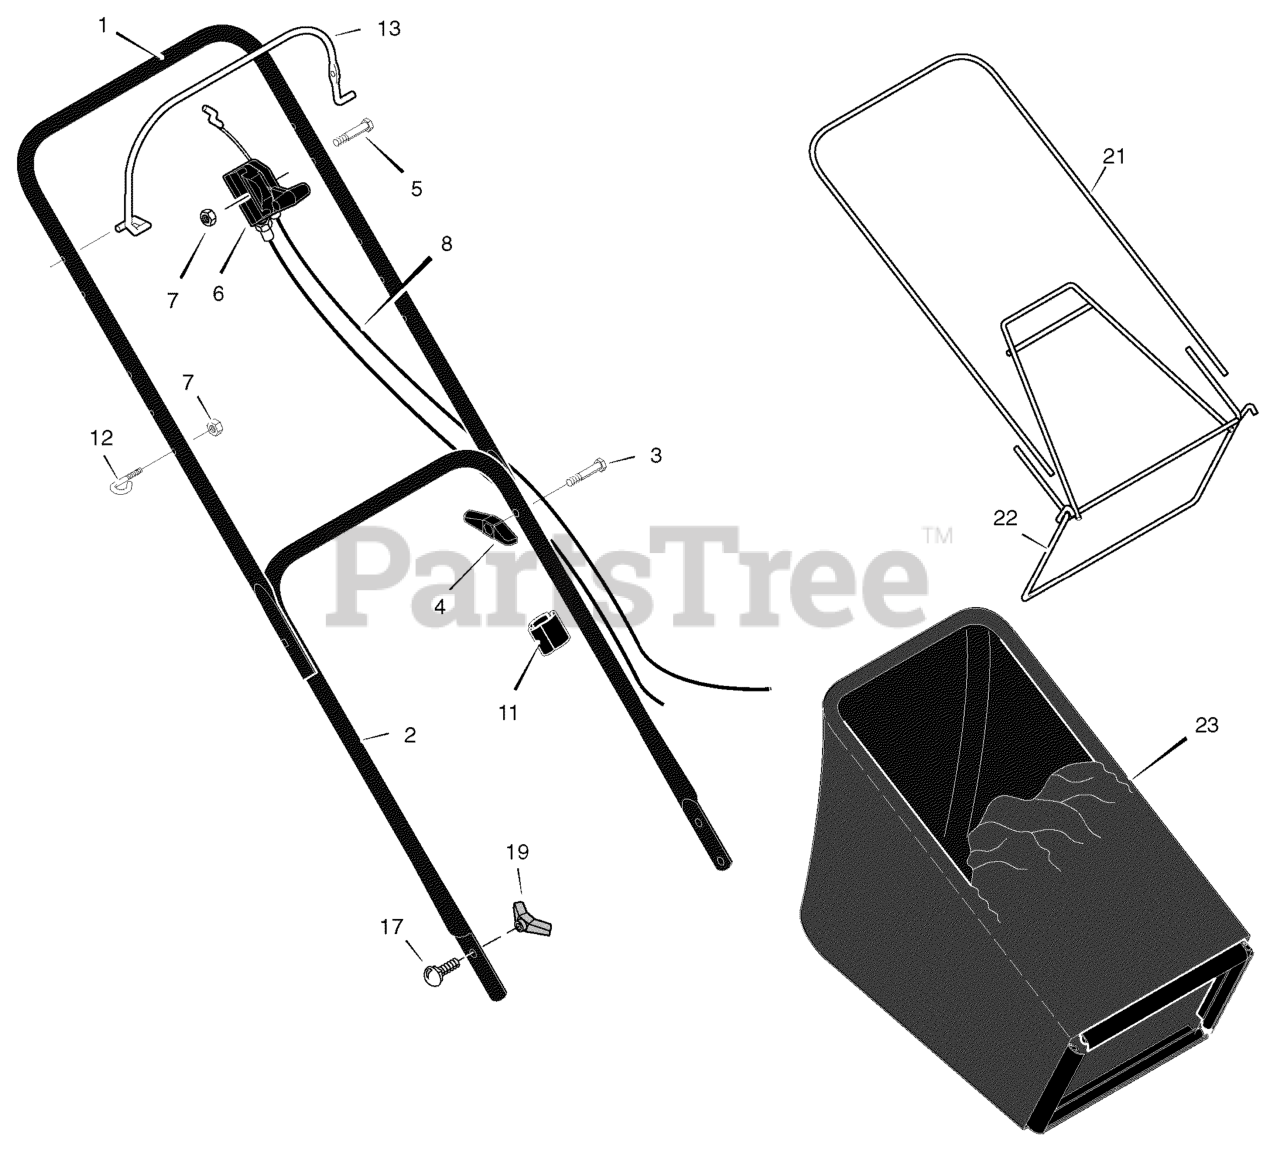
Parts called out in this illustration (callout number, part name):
1	Handle, Upper (Black)
2	Handle, Lower (Black)
4	Knob, Plastic
6	Throttle Control
7	Locknut
8	Engine Stop Cable
11	Clip, Cable
12	Guide, Rope
13	Lever, Engine Stop
17	Bolt, Carriage
19	Knob, Plastic
21	Frame, Top
22	Frame Assembly
23	Bag, Cloth
